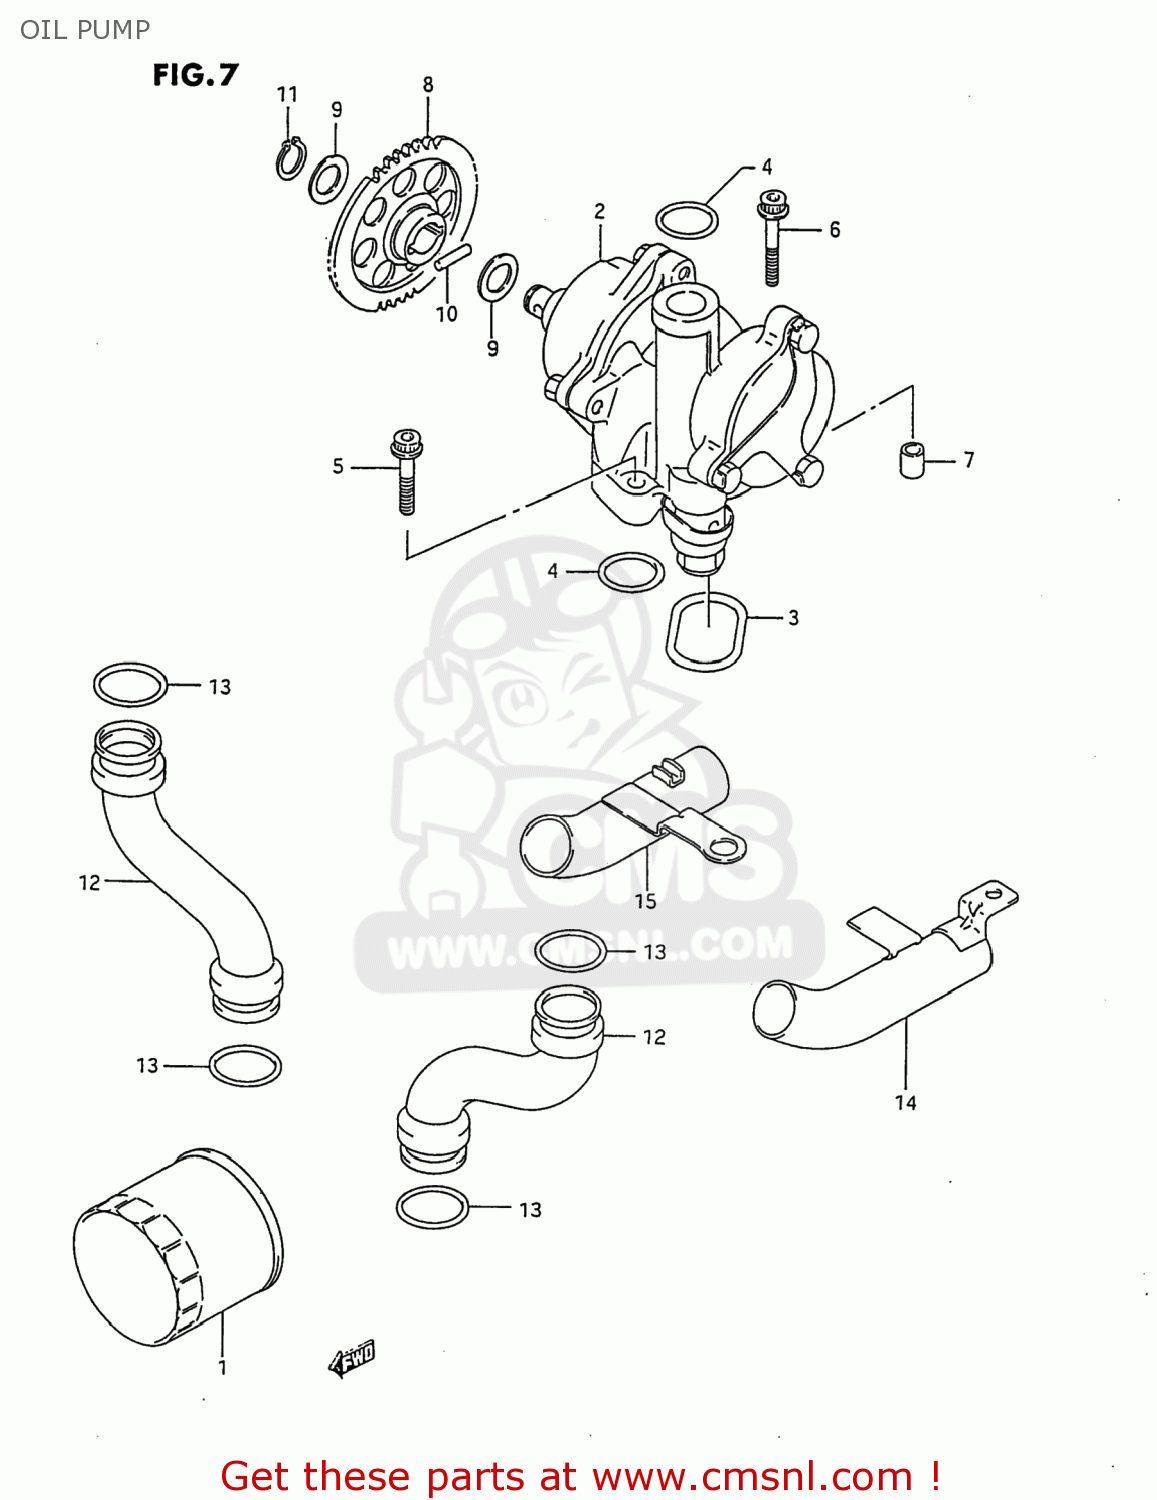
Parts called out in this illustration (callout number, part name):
1	FILTER ASSEMBLY,ENGINE OIL
2	PUMP ASSY,OIL
3	O RING,OIL PUMP
4	O RING(D:3.2,ID:17.8)
5	BOLT
6	BOLT
7	PIN
8	GEAR,OIL PUMP DRIVEN
9	SHIM
10	PIN(5X18)
11	CIRCLIP,12 MM
12	PIPE,OIL OUTLET
13	O RING(D:3.7,ID:21.7)
14	PIPE,OIL OUTLET UNDER,L
15	PIPE,OIL OUTLET UNDER,R
